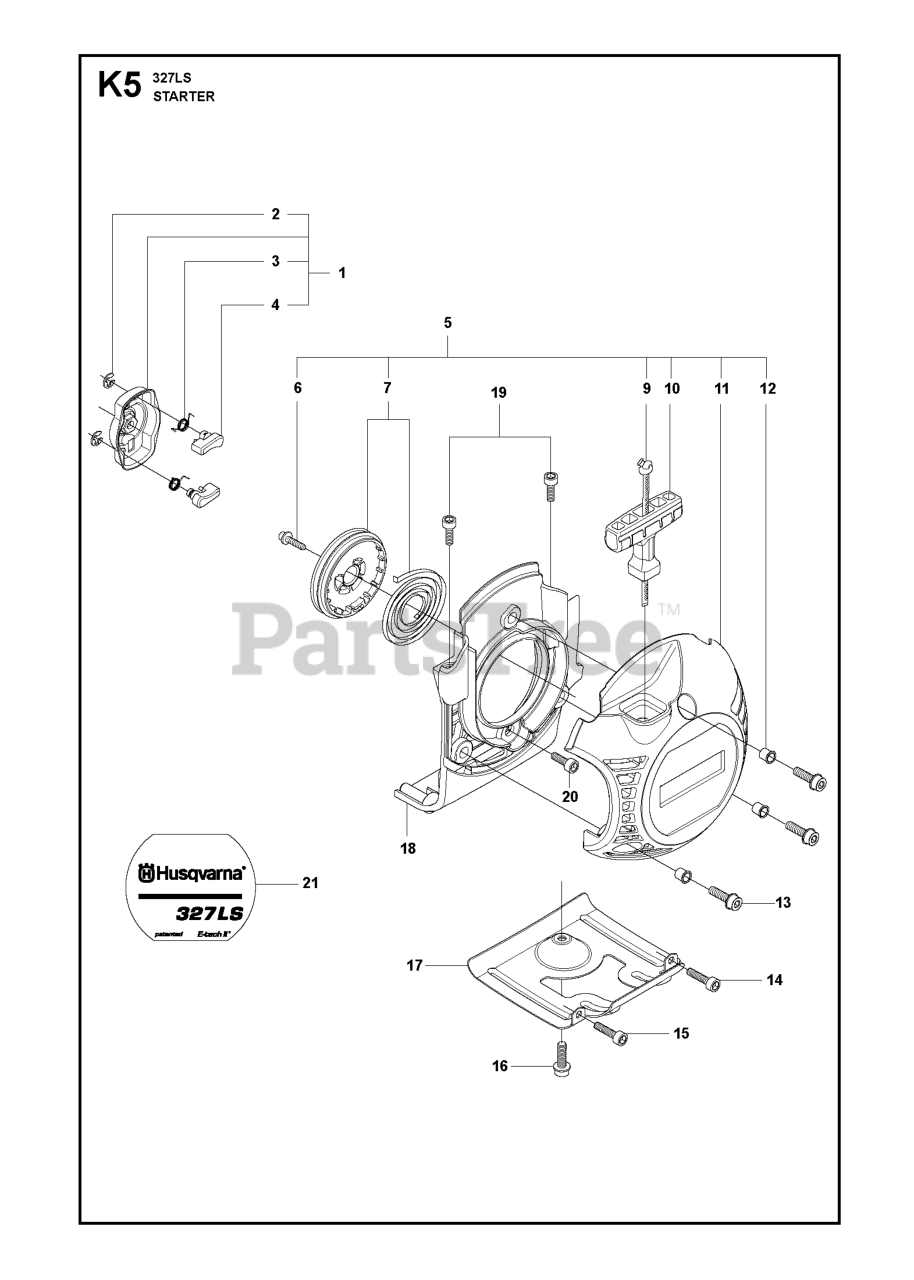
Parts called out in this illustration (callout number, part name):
1	STARTER PAWL BRIDGE
4	STARTER PAWL
5	STARTER ASSY
7	STARTER PULLEY
8	SPACING SLEEVE
9	STARTER ROPE
10	STARTER HANDLE
11	STARTER HOUSING
12	SPACING SLEEVE
13	SCREW
16	SCREW
18	BRACKET ASSY
